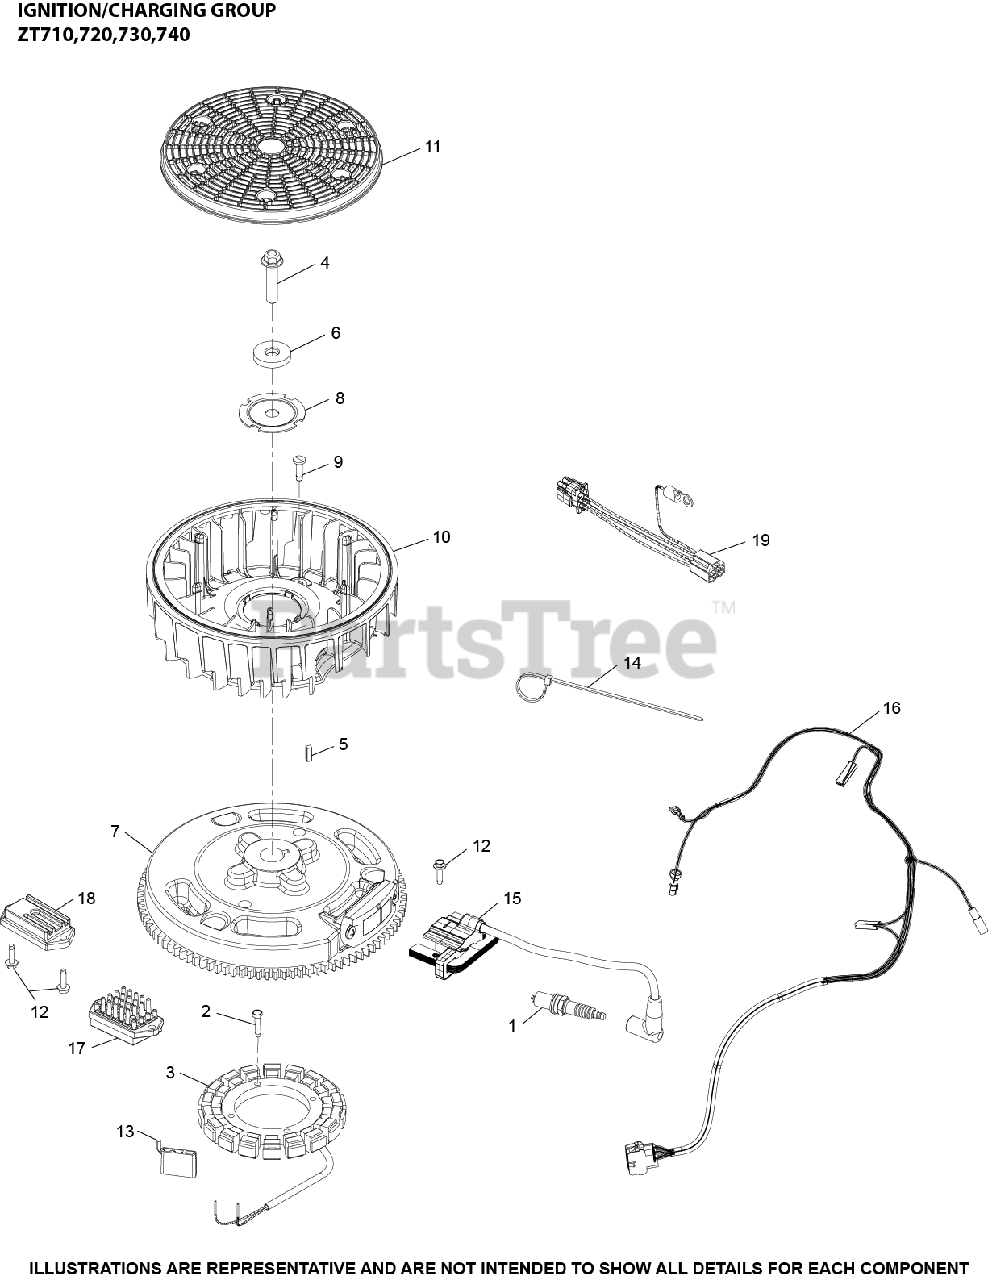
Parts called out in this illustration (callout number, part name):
1	PLUG, SPARK (STD)
2	SCREW, THREAD FORMING
3	KIT, 15 / 20 AMP STATOR
4	SCREW, HEX FLANGE
5	KEY, SQUARE
6	WASHER, FLAT
7	FLYWHEEL ASSEMBLY
9	RETAINER, FLYWHEEL FAN
12	SCREW, THREAD FORMING - USE 25 086 473-S
13	CONNECTOR
14	TIE, WIRE
15	MODULE, IGNITION
16	HARNESS, WIRING ASSEMBLY
18	RECTIFIER, UNREGULATED POWER SOURCE
